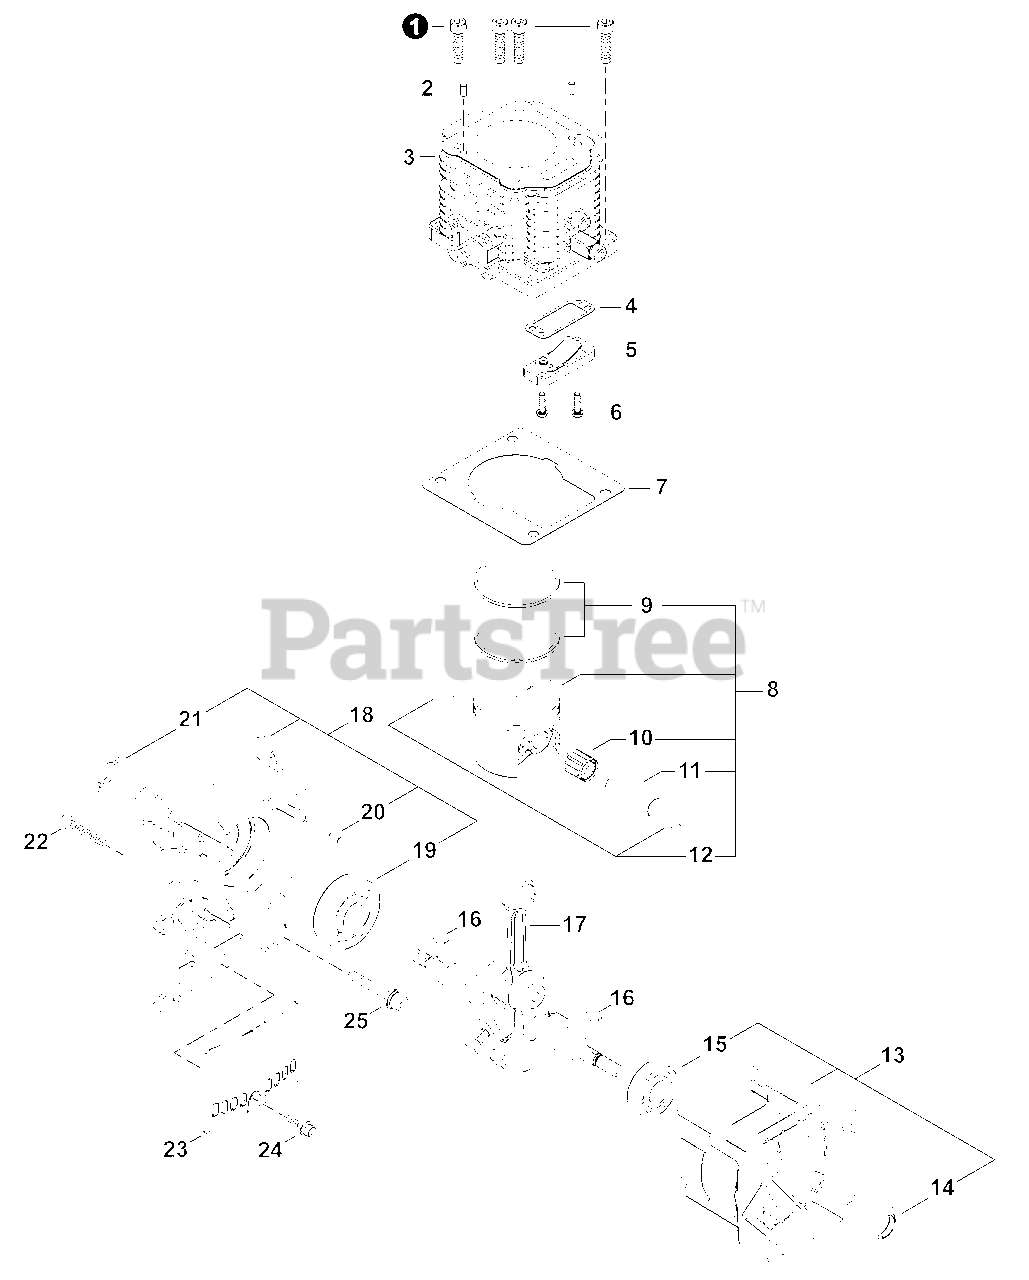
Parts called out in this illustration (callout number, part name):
1	BOLT 6×25
2	PIN, LOCATING 4×8
3	CYLINDER
4	GASKET, REED VALVE
5	VALVE ASSY, REED
6	SCREW M4×14
7	GASKET, CYLINDER
8	PISTON KIT
9	RING, PISTON
10	BEARING, NEEDLE 12
11	PIN, PISTON 12
12	RING, SNAP
13	CRANKCASE ASSY, S
14	SEAL, OIL 21
15	BEARING, BALL 6202 C3
16	KEY, WOODRUFF 3×10
17	CRANKSHAFT
18	CRANKCASE ASSY, M
19	BEARING, BALL 6303 C3
20	PIN, LOCATING 4×8
21	SEAL, OIL 21
22	BOLT 5×30
23	COVER, DUST
24	BOLT 4×20
25	BOLT, ADHESIVE M6×40
